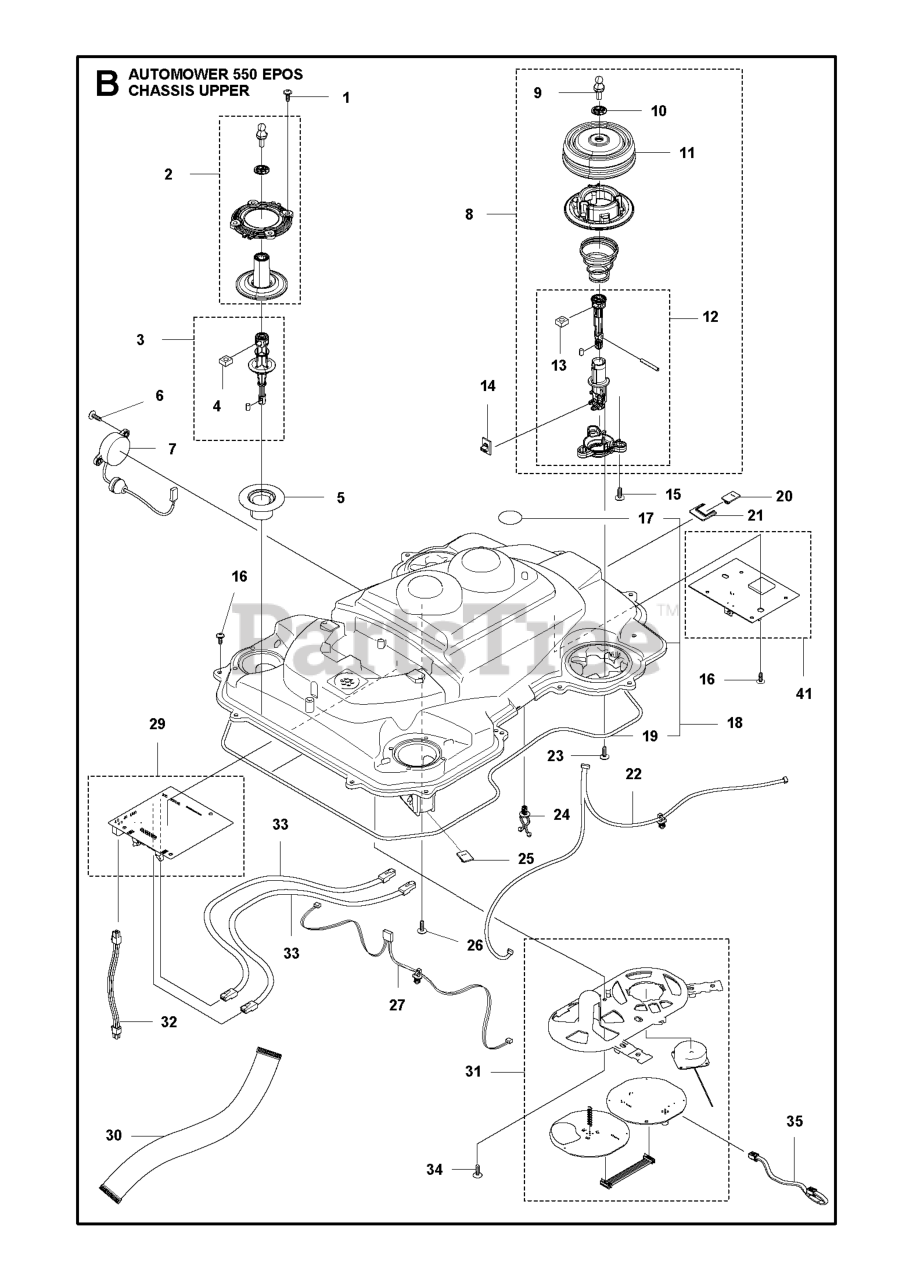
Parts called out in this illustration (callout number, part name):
1	SCREW ITXPANT
2	JOYSTICK KIT REAR
3	JOYSTICK KIT REAR
4	NUT
5	MOVEMENT LIMITER
6	SCREW 14MM
7	BUZZER ASSY
8	JOYSTICK KIT
9	STUD SNAPLOC
10	WASHER JOYSTICK
11	BELLOWS LIFT-COLLISION
12	JOYSTICK KIT
13	NUT
14	PRINTED CIRCUIT ASSY PCBA LIFT
15	SCREW 14MM
16	SCREW ITXPANT
17	KIT AIR FILTER KIT 305 - 10 PC
18	CHASSIS KIT UPPER 550 EPOS / 5
19	SEALING STRIP
20	PRINTED CIRCUIT ASSY COLLISION
21	CLIP COLLISION BOARD
22	WIRING ASSY LIFT SENSOR L1=670
23	SCREW ITXPANT
24	HOLDER TWIST LOCK
25	PRINTED CIRCUIT ASSY COLLISION
26	SCREW ITXPANT
27	1OOM KIT COLLISION SENSOR
29	PRINTED CIRCUIT ASSY PCBA APPL
30	LOOM MMI
31	HOLDER ASSY ANTENNA MODULE 915
32	WIRING ASSY HMI CABLE 4P L=33
33	WIRING ASSY MODULAR JACK 6/6 R
34	SCREW 14MM
35	Wires
